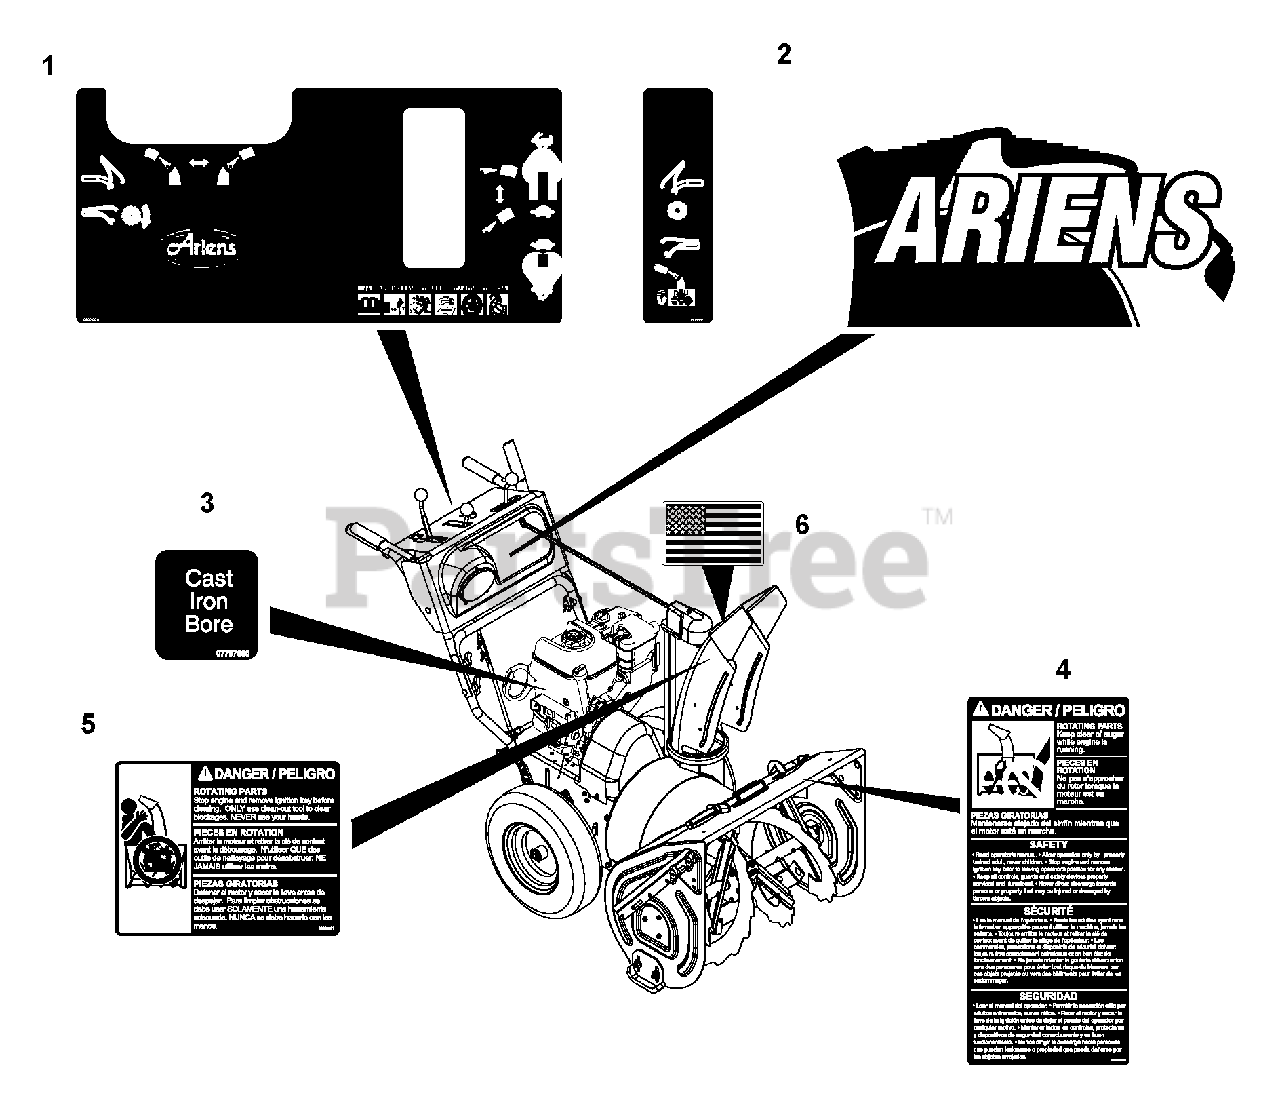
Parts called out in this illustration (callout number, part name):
1	DECAL, CONTROL
2	DECAL, FRONT DASH-926LE
3	DECAL - CAST IRON BORE
4	DECAL, DANGER
5	DECAL, DANGER - ROT. PARTS
6	DECAL, AMERICAN FLAG
